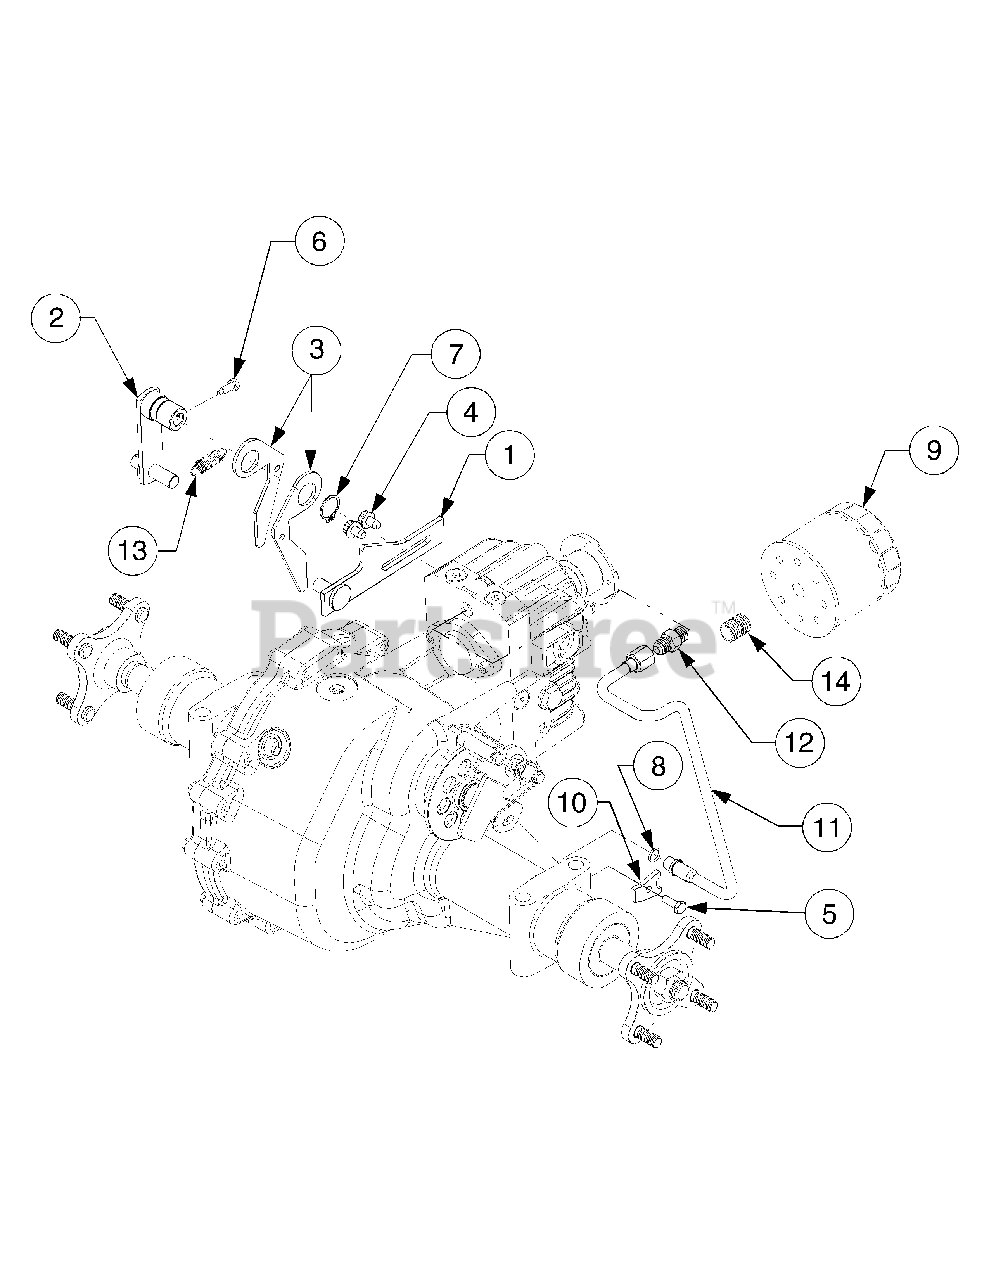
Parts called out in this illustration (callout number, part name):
1	Bracket, Neutral Return
2	Arm Assembly, Control
3	Arm, Neutral
4	Screw, Hex Wash Hd Tapp, 5/16-18 x .50
5	Screw, Hex Cap, 1/4-20 x .75 GR5
6	Screw, Special Hex Cap, 5/16-24 x .625
7	Ring, Snap, .875 Shaft
8	O-Ring, .426 ID x .566 OD x .07
9	Filter, Oil
10	Clamp, Tube, .50
11	Tube, Hydro Pickup
12	Fitting, Hydraulic
13	Spring, Extension
14	Nipple, Oil Filter
